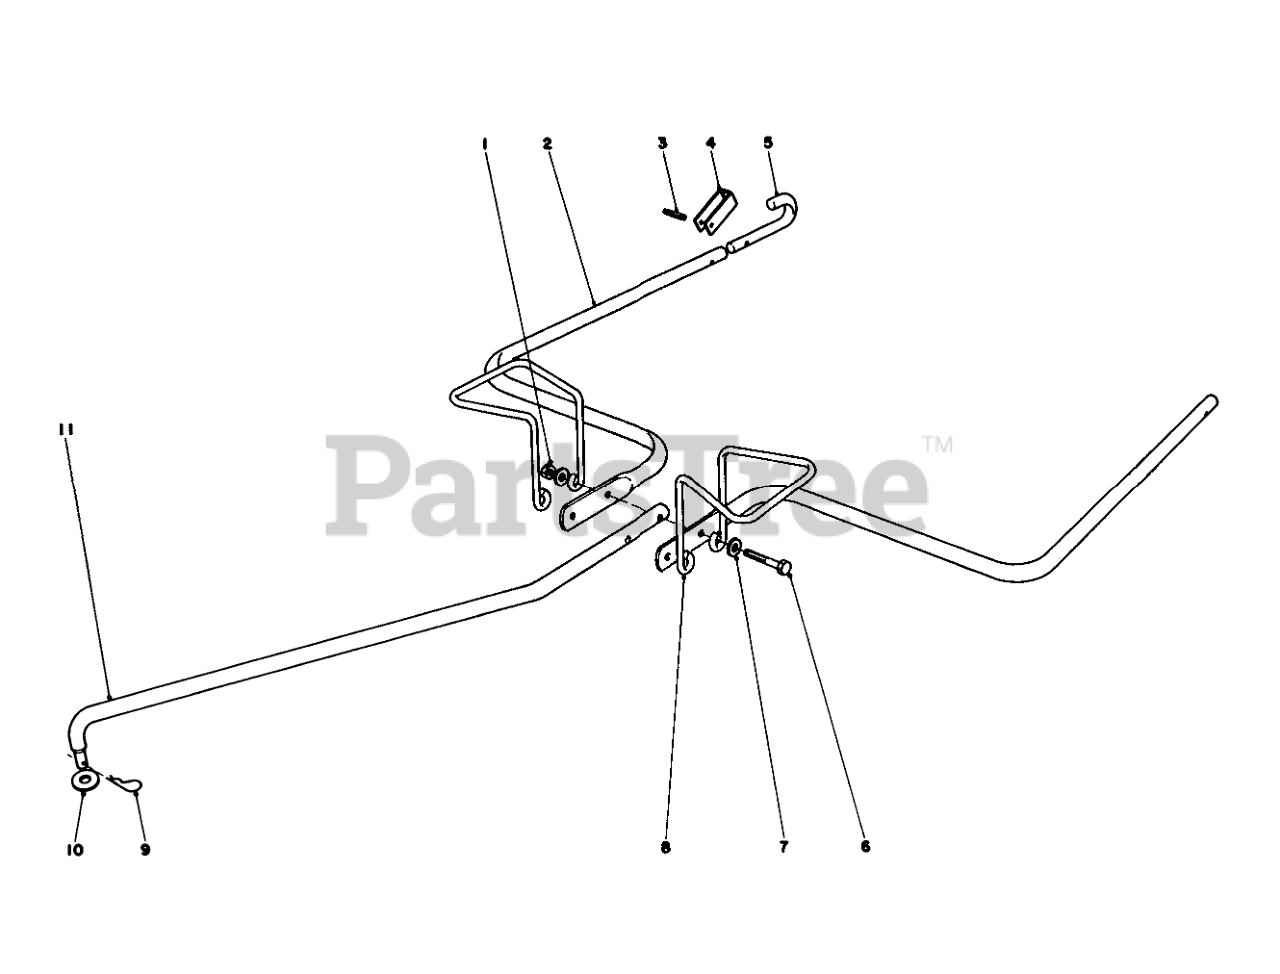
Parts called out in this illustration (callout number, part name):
1	NUT-LOCK, CONE
2	HITCH ARM
3	PIN-ROLL, SLOT
4	HITCH LOCK
5	HOOK HITCH ARM
6	SCREW-HH
7	WASHER-FLAT
8	Support Bag
9	PIN-COTTER
10	PUSH NUT
11	POLE HITCH
